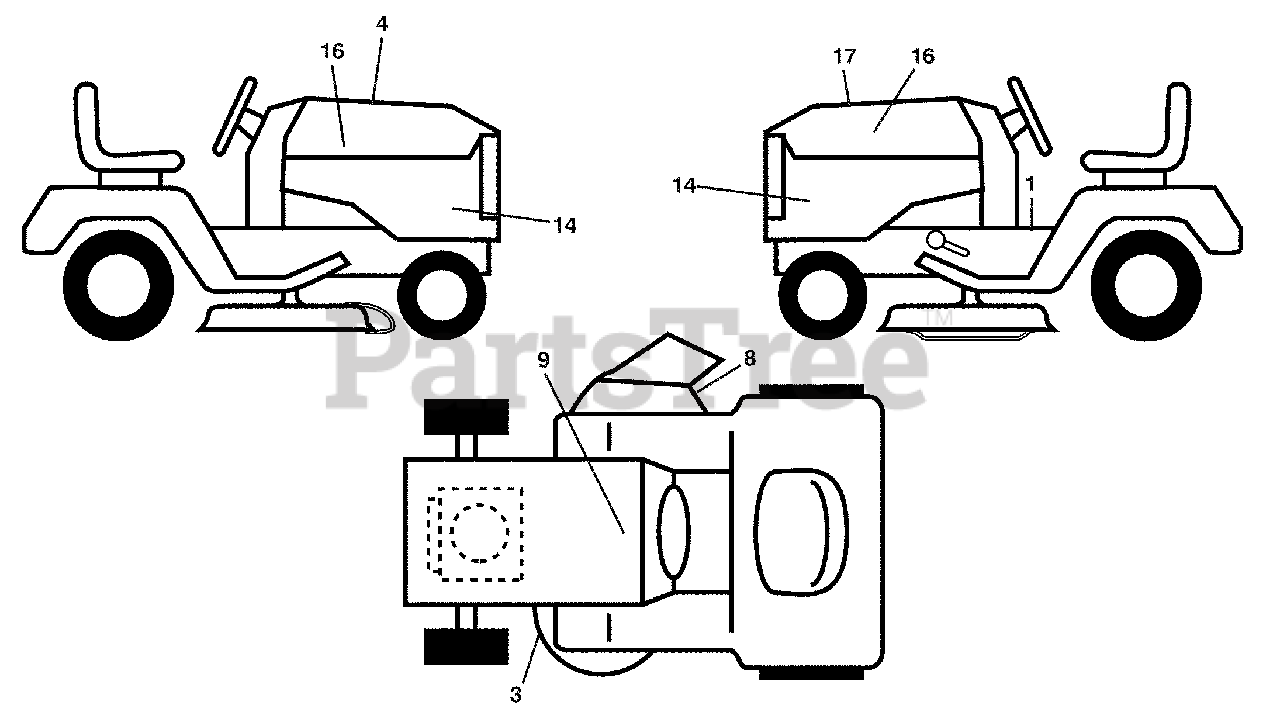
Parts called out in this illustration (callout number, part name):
1	Decal, Fender Warning
3	Decal, Warning
4	Decal, Hood Cust Resp
8	Decal, Mower Sch.
9	Decal, Battery Dnge/Poi
14	Decal, Panel Side
16	Decal, Hood Logo
17	Decal, Replacement
18	Decal, Bypass
19	Pad, Footrest, LH
20	Pad, Footrest, RH
